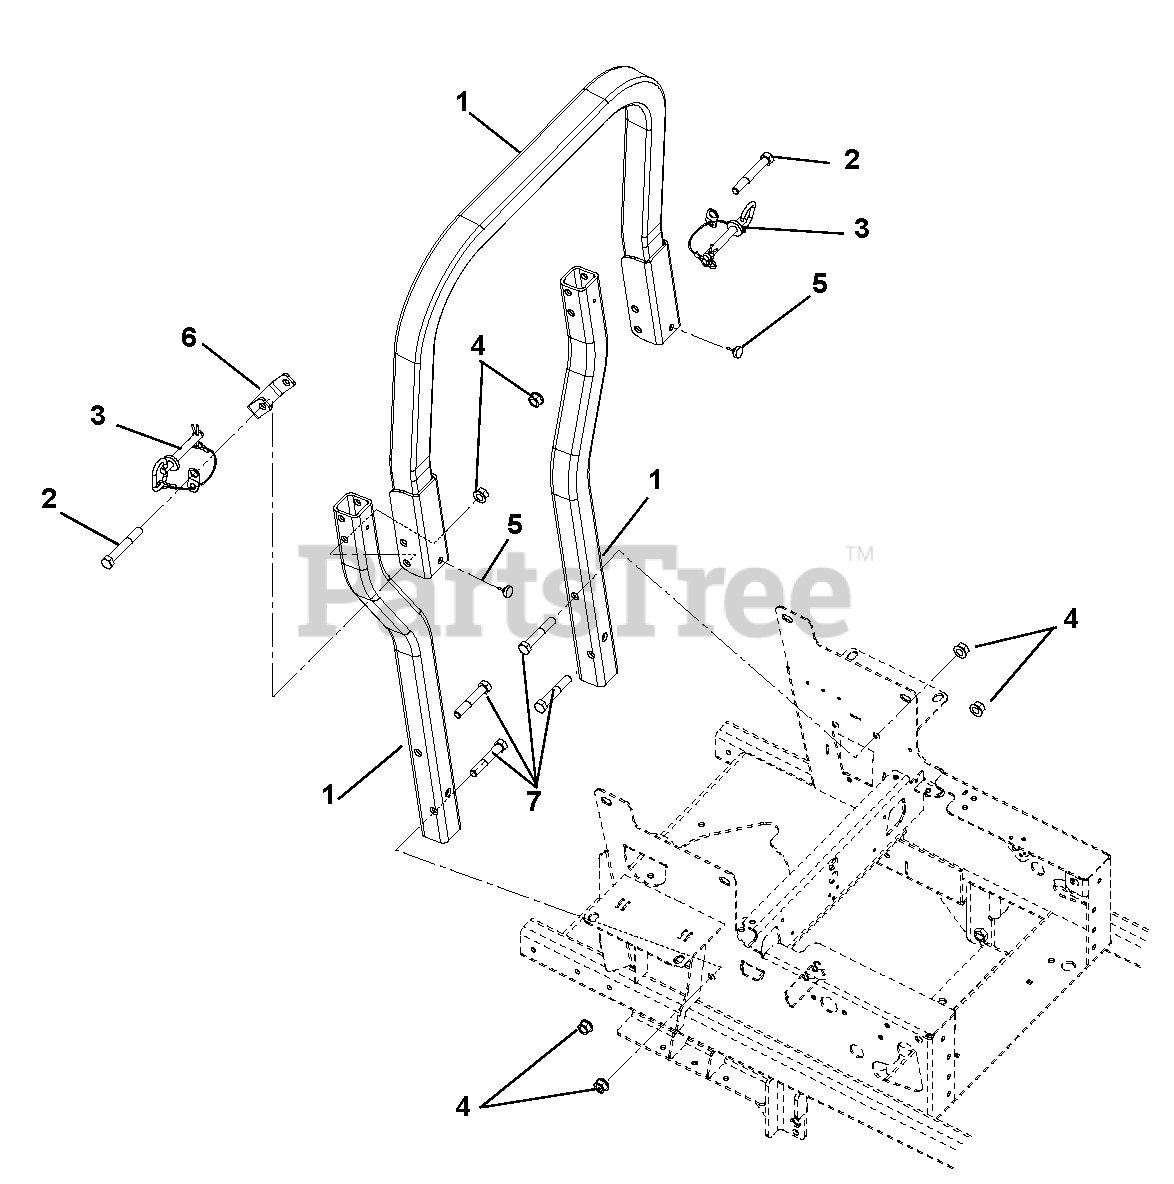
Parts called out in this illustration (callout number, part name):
1	ROPS, PT100 Replacement
2	Bolt, Hex .50-13 x 3.50
3	Assembly, ROPS Pin/Lanyard
4	Nut, Locking Top Flange .50-13
5	Bumper, ROPS Rubber
6	Bracket, ROPS Stop, Pro-Turn
7	Bolt, Hex .50-13 x 3.00
